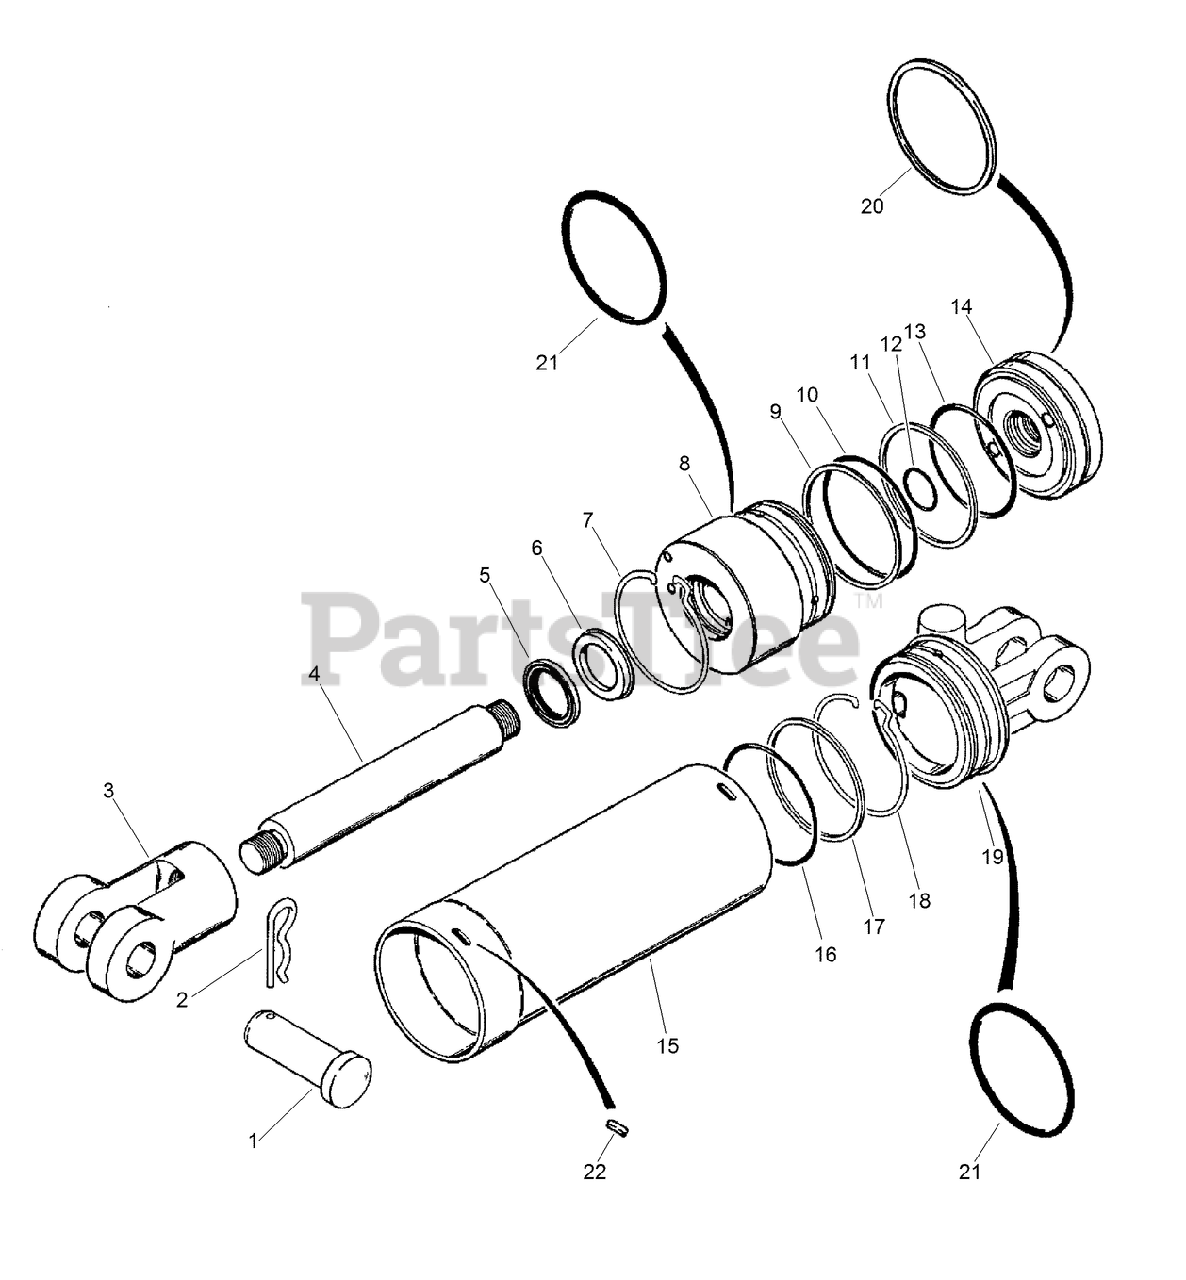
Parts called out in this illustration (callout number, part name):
1	PIN-upset clevis
2	PIN-COTTER, QUICK ATTACH
3	END-piston rod
4	ROD-piston
5	WIPER-piston rod
6	SEAL-U-cup, piston rod
7	RING-locking
8	GLAND-cylinder
9	RING-backup, gland O-ring
10	O-RING-gland
11	SEAL-piston, outer
12	O-RING-piston rod
13	O-RING-piston
14	PISTON-cylinder
15	TUBE-cylinder
16	O-RING-cylinder tube
17	RING-backup, cylinder tube O-ring
18	RING-locking
19	HEAD-cylinder
20	RING-wear, piston
21	O-RING-tube to gland and head
22	COVER-slot, locking ring
